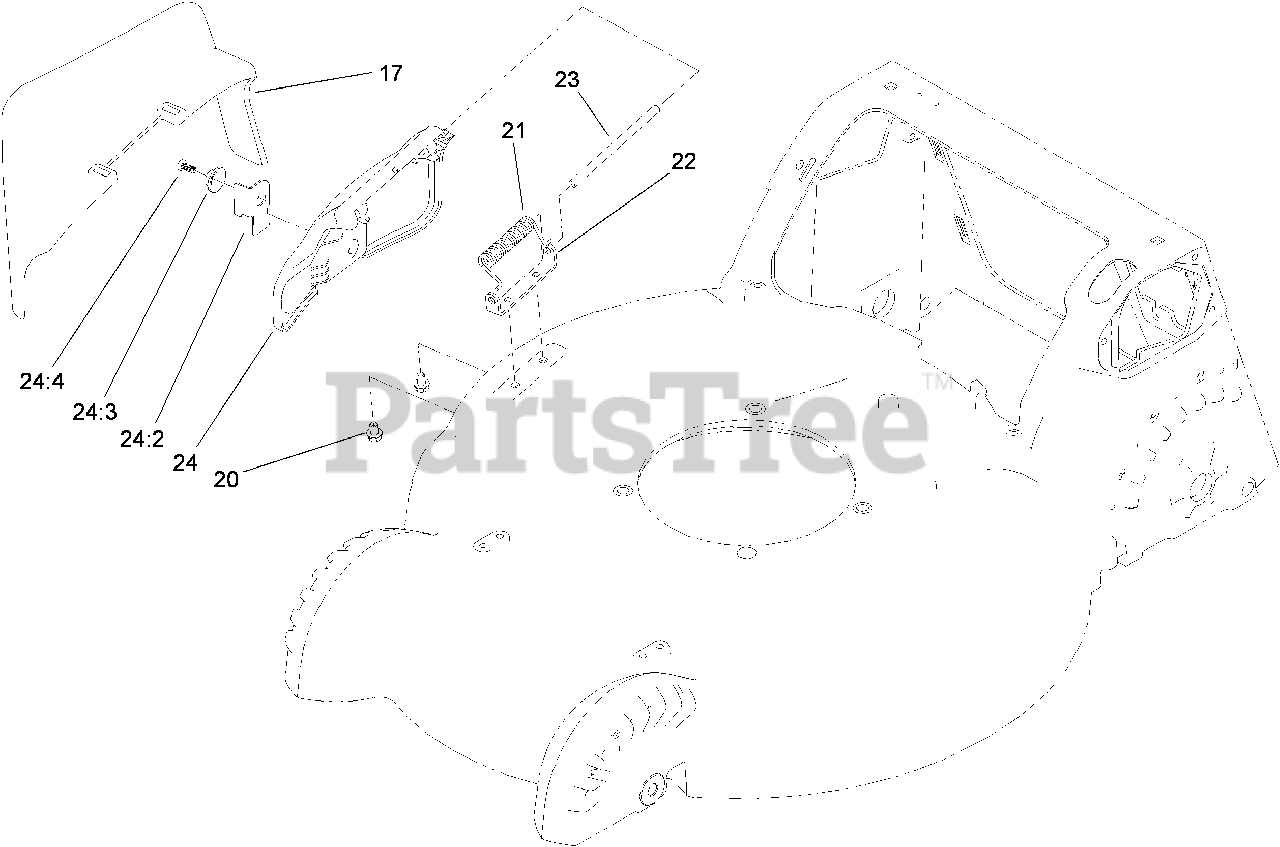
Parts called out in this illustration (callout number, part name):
17	CHUTE-DISCHARGE, SIDE
20	SCREW-HWH
21	SPRING-TORSION
22	BRACKET-COVER
23	ROD-COVER
24	DISCHARGE DOOR ASM
24:2	LATCH-DOOR
24:3	CAP-DOOR
24:4	SCREW-PLASTITE
